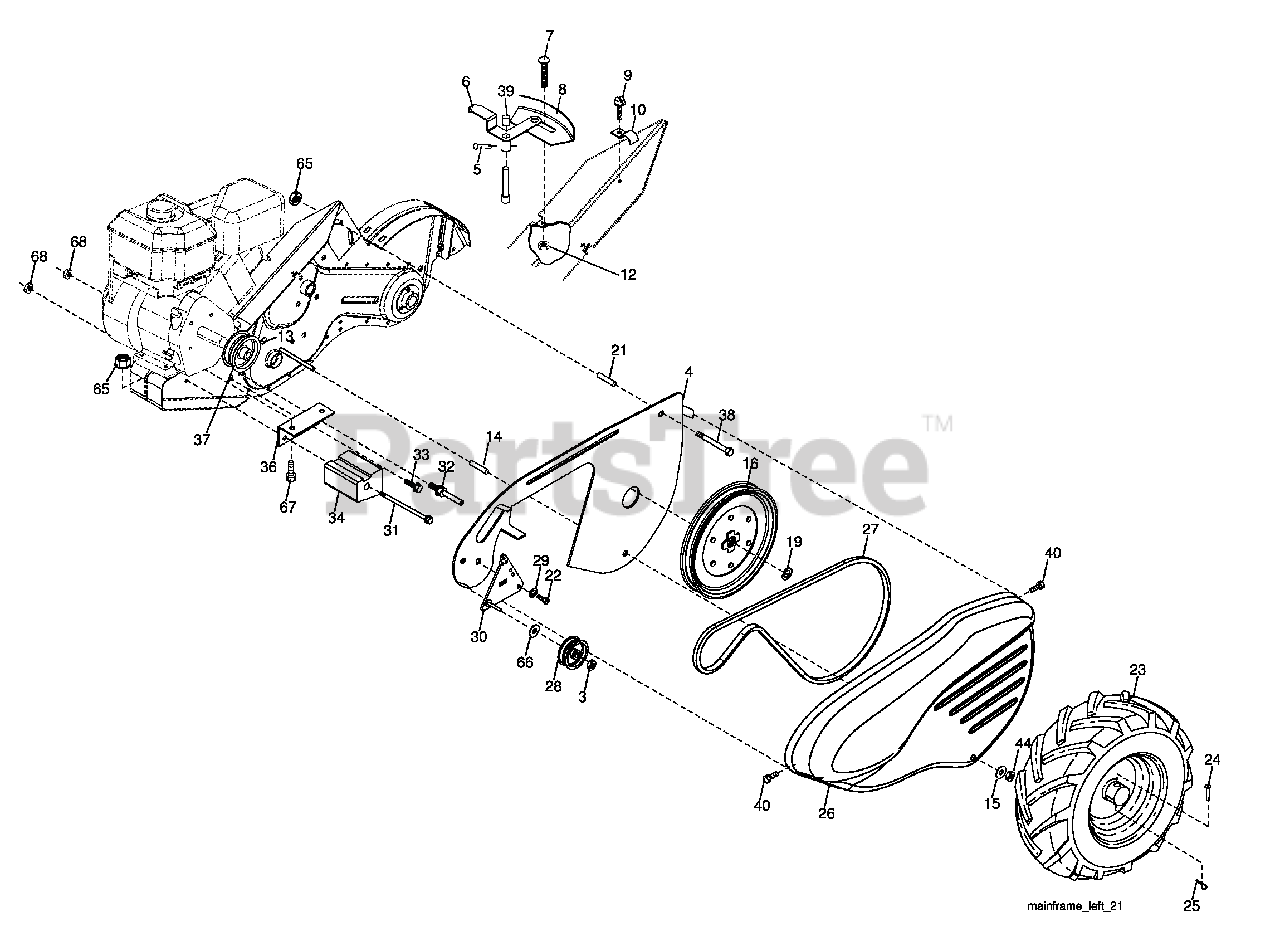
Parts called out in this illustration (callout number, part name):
3	Nut, Hex 3/8-16
4	Shield, Inner Belt Guard RT
5	Pin Spirol Flared
6	Lever, Shift
7	Bolt, Carriage 1/4-20 x 1/2 Gr. 5
8	Plate, Shift Indicator
9	Screw, Hex, Washer Head, Slotted #10-24 x 1/2
12	Nut, Keps Hex 1/4-20 unc
13	Screw, Set, Hex 5/16-18 x 3/8
14	Spacer, Split 0.327 x 0.42 x 2.09
15	Washer 11/32 x 11/16 x 16 Ga.
16	Sheave, Transmission
19	Retainer, Ring
21	Spacer, Split
22	Bolt, Fin Hex 5/16-24 unf x 1/2
24	Rivet, Drilled
25	Clip, Hairpin
26	Guard, Belt
27	Belt, V
28	Pulley, Idler
29	Ring, Klip
30	Bracket, Idler
31	Bolt, Hex 3/8-16 x 10
32	Shaft, Idler Arm
33	Bolt, Hex 3/8-16 x 1
34	Counterweight,
36	Bracket, Reinforcement, L. H.
37	Sheave, Engine
38	Bolt, Fin Hex 5/16-18 unc x 2-3/4
39	Cap, Plunger Blk
40	Screw Hex Wsh Slt #10-24 x 1/2
44	Nut Lock Hex w/Ins 5/16-18 unc PL
65	Nut Lock Hex Flange
66	Washer 13/32 x 13/16 x 12 Ga.
67	Bolt, Hex 5/16-18 x 1-1/2
68	Nut, Keps Hex 3/8-16 unc
